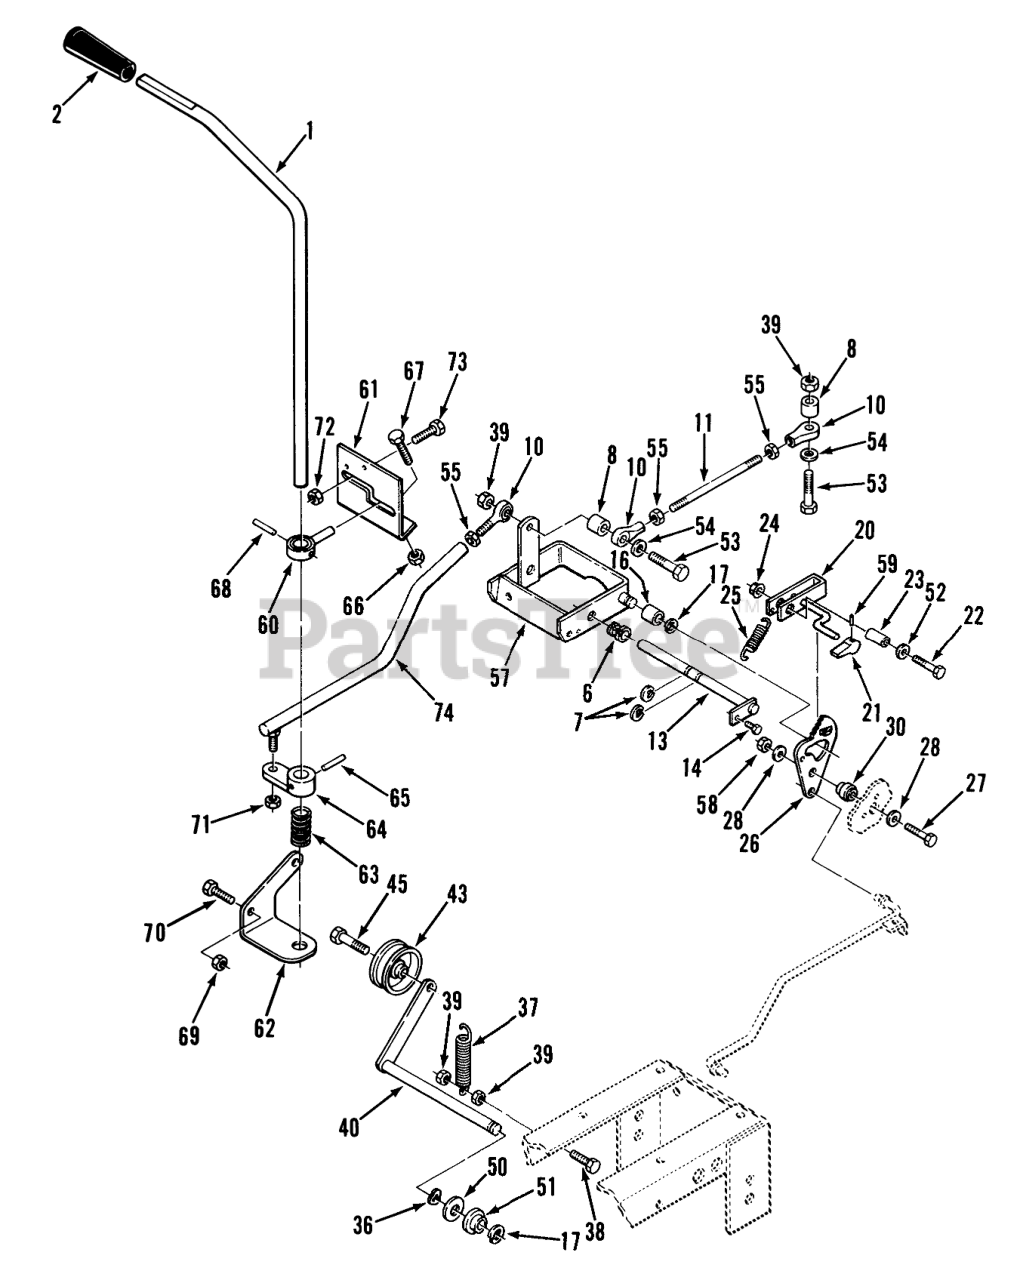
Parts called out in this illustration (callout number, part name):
1	ROD-MOTION CONTROL
2	Knob-Motion Control
6	NYLINER BUSHING
7	E Ring
8	Spacer
10	ROD END, 1/4-28
11	ROD-CONTROL
13	ASSY-ROD CAM PIVOT
14	SCREW
16	BEARING-CAM RETURN
17	E Ring
20	WLDMT-BRAKE PAWL B
21	KNOB-PARKING BRAKE
22	Bolt
23	SPACER
24	LOCKNUT-FLANGE
25	Spring
26	Cam Plate
27	BOLT
28	Washer
30	Spacer
36	WASHER-WAVE
37	SPRING-EXTENSION
38	Bolt
39	Nut
40	Pivot Rod
43	PULLEY-IDLER
45	BOLT-SPECIAL HEX
50	Washer
51	BUSHING-FLANGED
52	Washer
55	Jam Nut 1/4-28
57	Cam Comtrol
58	NUT
59	PIN-SPIROL 3/32X5/8
60	GUIDE-CONTROL
61	Control Bracket
62	BRKT-LOWER CONTRO B
63	SPRING-COMPRESSION
64	ARM-CONTROL
65	Spirol Pin
66	Nut
67	Bolt
68	SPIROL PIN 7/32X7/8
69	Nut
70	Bolt
71	5/16-24 E.S. NUT
72	Nut
73	Bolt
74	ASSY-ROD & BALL JOINT
